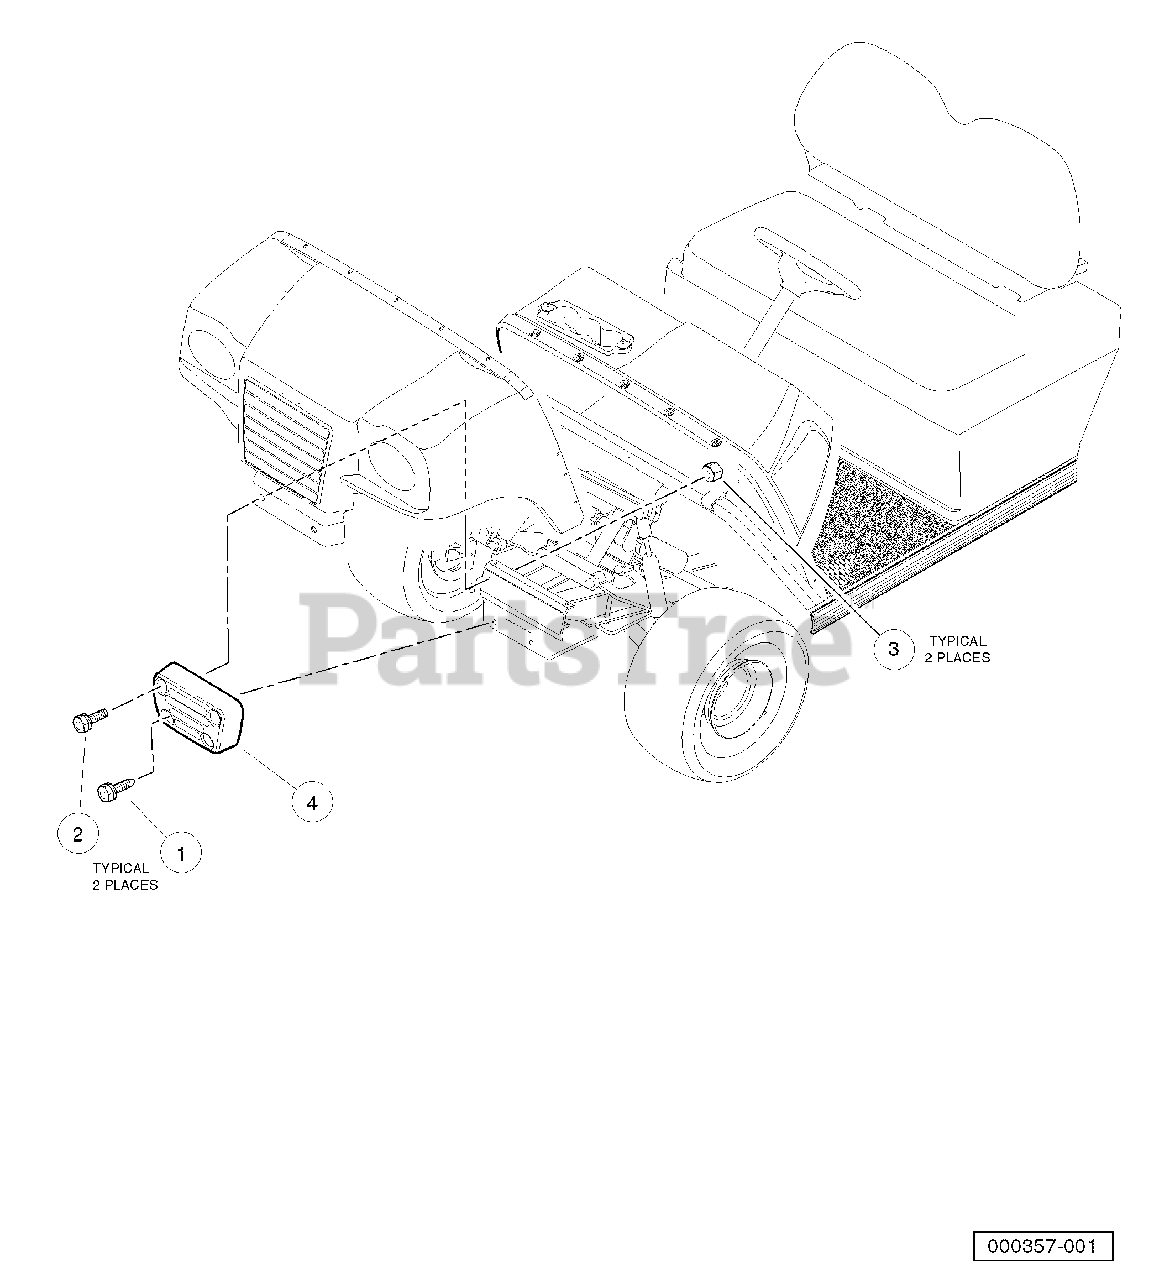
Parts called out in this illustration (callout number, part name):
1	Screw, M8 X 1.25 X 30 Tri, Blk
2	Bolt, Flange Head, M8-1.25 X 40
3	Lock Nut, Flg M8 X 1.25 Nylon
4	Bumper Cast
